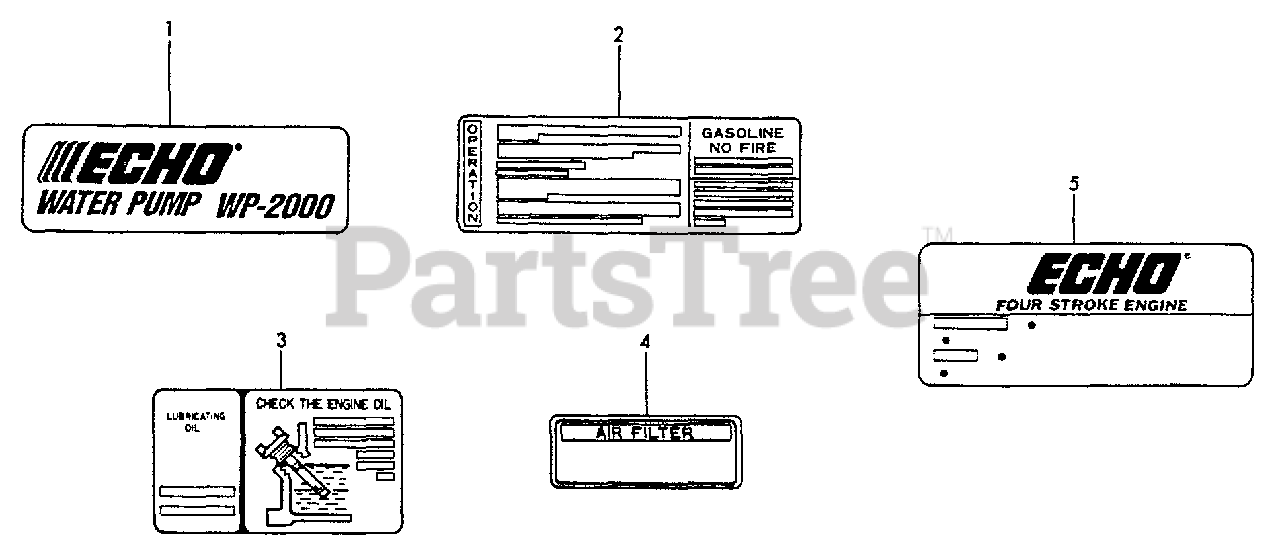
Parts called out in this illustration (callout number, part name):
1	LABEL - MODEL WP2000
2	LABEL - OPERATION
3	LABEL - OIL
4	LABEL - AIR CLEANER
5	LABEL - ECHO
